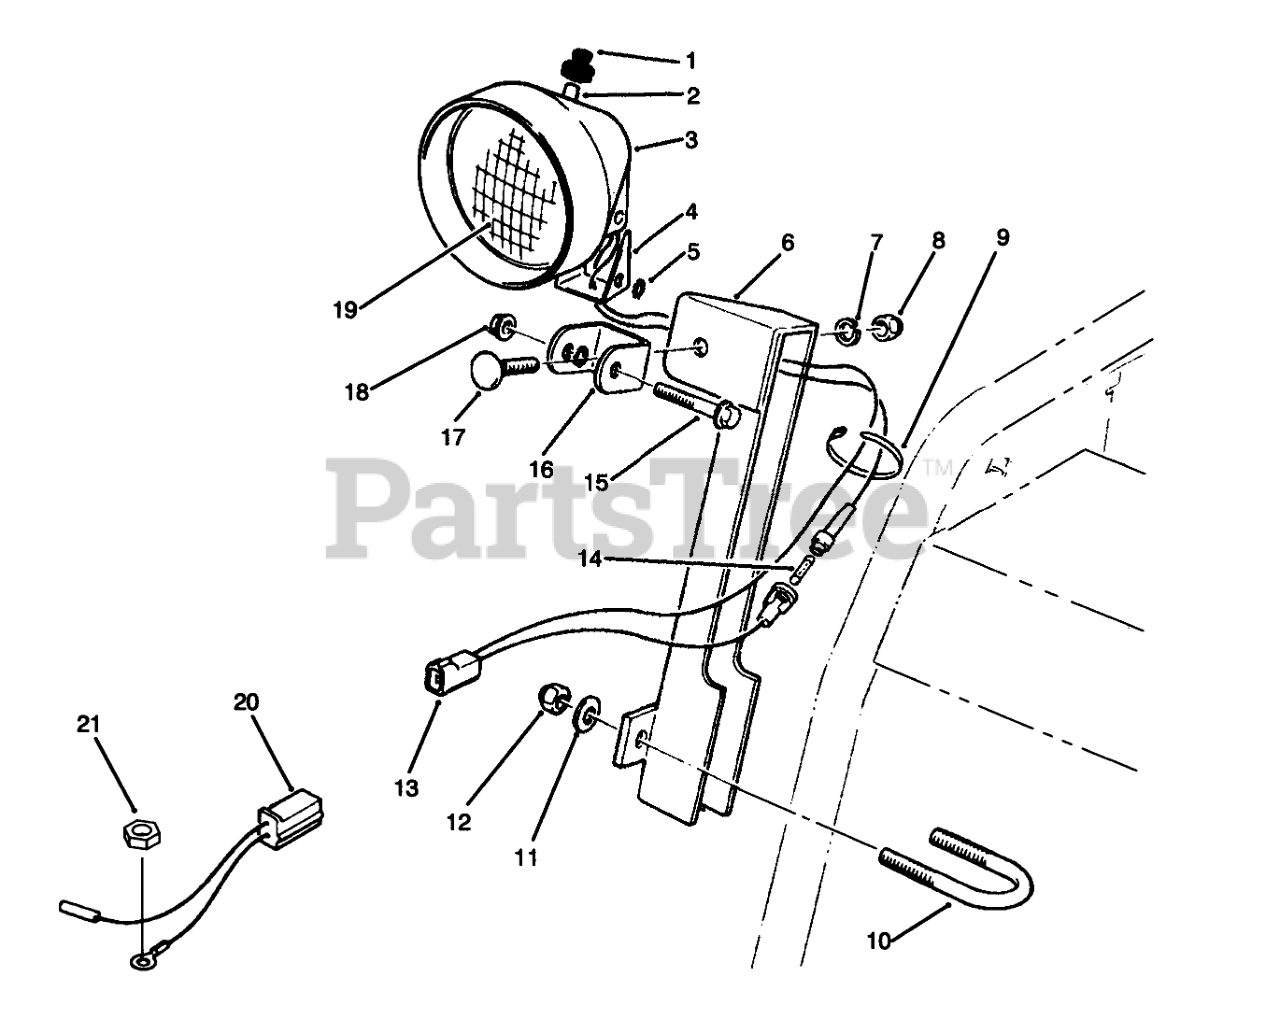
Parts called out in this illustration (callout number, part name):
1	BOOT-SWITCH
2	SWITCH ASM
3	Bucket-Headlamp
4	TO BE DISCONTINED-NOT NEEDED ON PRODUCT
5	WASHER-LOCK
6	Mount-Lamp
7	WASHER-LOCK
8	NUT-HEX
9	TIE-CABLE
10	U-BOLT
11	WASHER-PLAIN
12	NUT-LOCK, NI
13	Wire Assembly
14	Fuse-7-1/2 Amp.
15	SCREW-HH
16	BRACKET
17	BOLT-CARR
18	NUT-HF
19	SEALED BEAM
20	WIRE ASM
21	NUT-HEX
